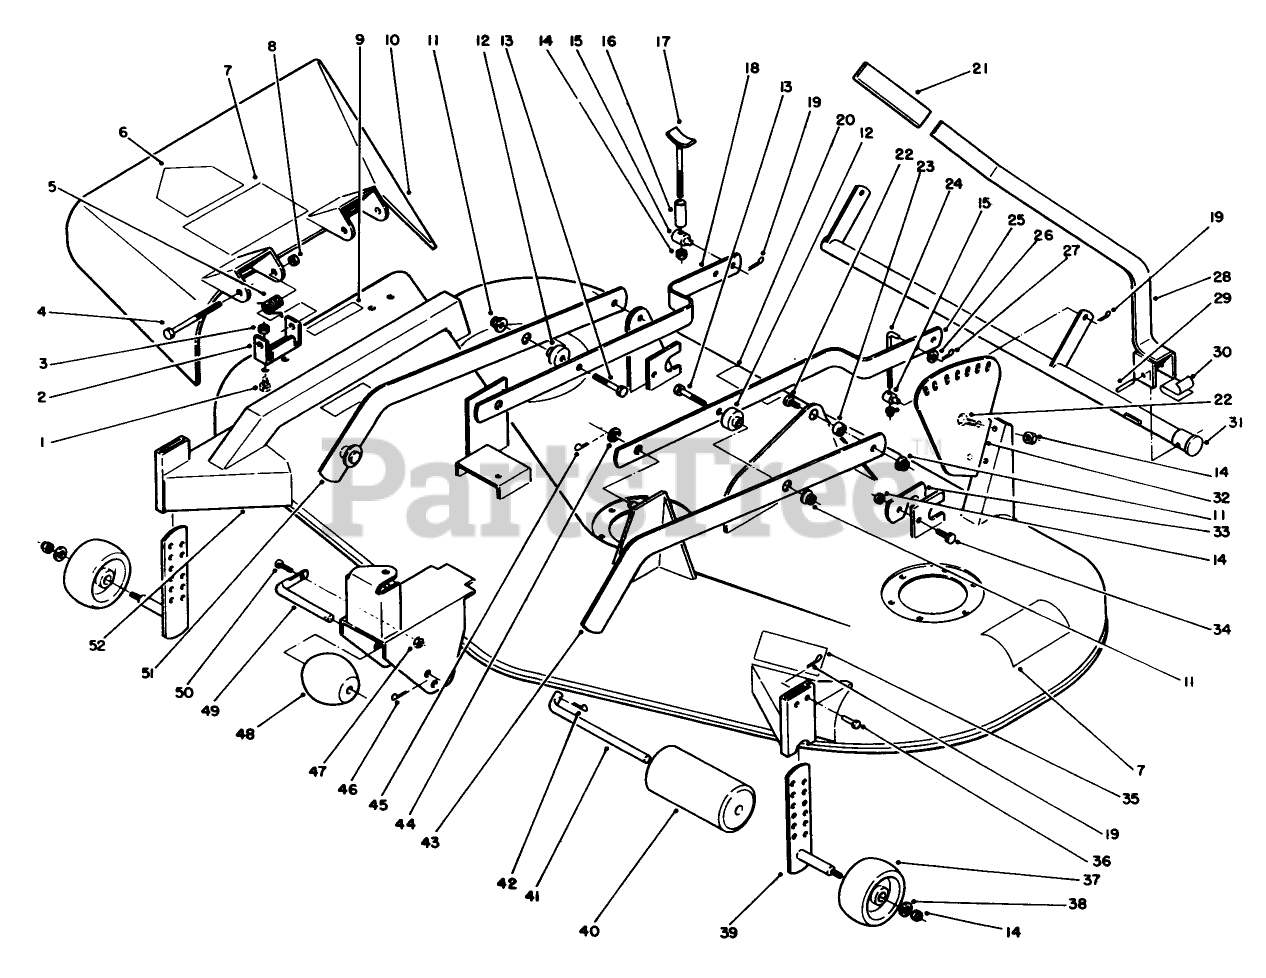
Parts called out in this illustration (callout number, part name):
1	Bolt Carnage
2	Bracket-Pivot
3	Nut
4	SCREW-HH
5	SPRING
6	DECAL-DANGER
7	DECAL-DANGER, THROWN OBJECT
8	NUT-HEX
9	DECAL-DANGER
10	Deflector Assembly (Incl. Ref. #6 & 7)
11	LOCKNUT-FLANGE
12	SPACER
13	Bolt
14	NUT
15	TRUNNION
16	SPACER .375 ID X 1.6
17	WLDMT-HANGER ROD
18	Bar-Leveler
19	Hairpin Cotter
20	DECAL-BELT ROUTING
22	Bolt
23	SPACER
24	ROD-LIFT
25	Draft Bar RH
26	WASHER 5/16 SAE
27	Cotter Pin
28	Lever
29	SPIROL PIN
30	CLIP-SPRING
31	Lit Arm Assembly
32	Quadrant
33	LOCK-SHAFT
34	Bolt
35	DECAL - WHEEL ADJUSTMENT
36	PIN-CLEVIS
37	WHEEL-GAGE
38	WASHER-FLAT
39	GAGE-WHEEL
40	ROLLER-DECK
41	SHAFT-ROLLER, REAR
43	Draft Bar LH
44	WASHER
45	PIN-4
46	Cotter Pin
47	Nut
48	ROLLER
49	SHAFT-ROLLER
50	Bolt
51	Draft Bar RH
52	Deck Assembly
